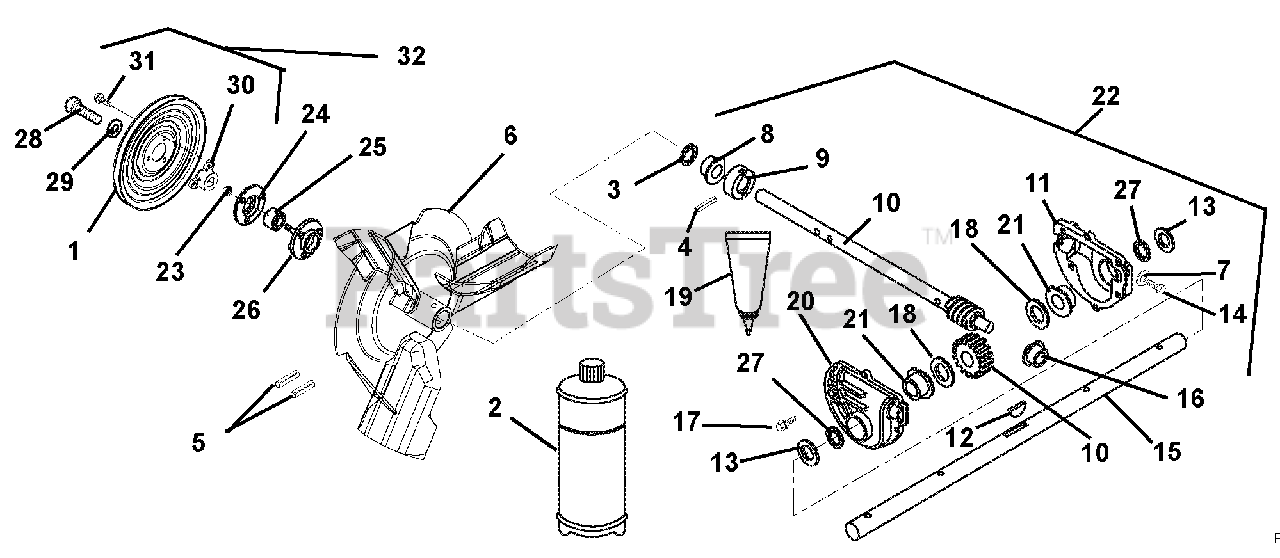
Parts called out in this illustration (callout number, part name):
1	PULLEY,SPIN FORM SINGLE GROOVE
2	ARIENS L3 LUBE, 8 OZ BOTTLE
3	SEAL-OIL.748X1.378X.276 RBR OD
4	@PIN-GRV .188X1.25 TP E ALLOY
5	PIN-ROLL .250X1.75
6	IMPELLER, COMPACT 12" 3-BLADE
7	WSHR-FIBER .437X.656X.032
8	BSHG-FLG .750X1.000X.750X1.250
9	THRUST COLLAR, .75" ID
10	SHAFT AND WORM GEAR ASSEMBLY
11	GEARCASE CASTING, MACHINED LH
12	KEY-WDRF .19X.63 HRD #61
13	@WSHR-FL-STL.812X1.50X.135YWZC
14	SCR-TAP .38-16X.75 ROLOK YZ WX
15	SHAFT, RAKE - 22" (.750 DIA)
16	BSHG-FLG .502X1X.750
17	@SCR-TAP .25-20X1.00 HWH TR YZ
18	WSHR-FL-STL.755X1.375X.062YWZC
19	LOCTITE 518 GASKET--6ML TUBE
20	GEARCASE CASTING, MACHINED RH
21	BSHG-FLG .753X1.127X.500X1.501
22	GEAR CASE ASSEMBLY - 22" ALUM.
23	@NUT-LK-CTR .25-20 YWZC
24	BEARING FLANGE
25	BRG-BALL .750X1.750X.50
26	BEARING FLANGE
27	SEAL-OIL .750X1.375X.250
28	BLT-HEX .31-24X.75 YWZC GR5
29	WSHR-LK .312X.097 HVY YWZC
30	PULLEY HUB, BOLT-ON D-BORE .75
31	@SCR-TAP .31-18X.50 HWH TR YWZ
32	PULLEY WITH HUB
